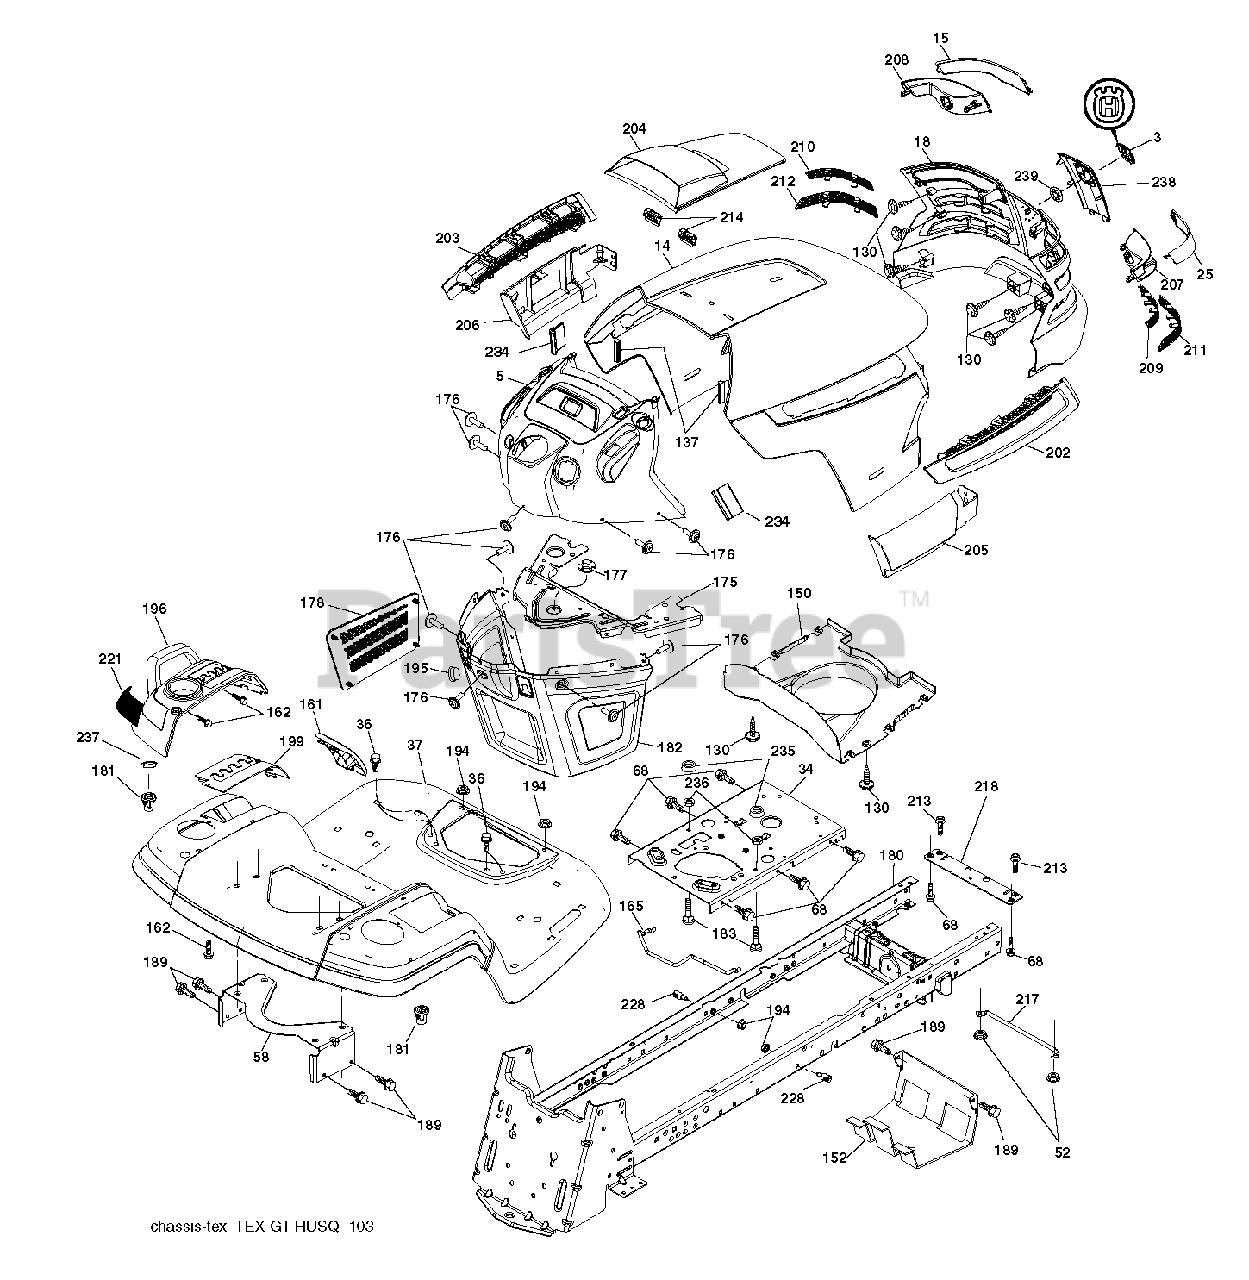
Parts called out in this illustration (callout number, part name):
3	LOGO.HUSQ.GT.LT.CROWN.H
14	HOOD
15	LENS.LH.TEX.GT.HUSQ.CL
18	GRILL.ASM.HUSQ.TG/CRD.W/TRIM
25	LENS.RH.TEX.GT.HUSQ.CL
34	PLATE.ENGINE.WELDED.CHASSIS
36	SCREW 5/16"
37	FENDER.PNT.TX.GT.CH/FW/DL.HUSQ
52	LOCKNUT
58	BRKT.SUPPORT.FNDR/TANK
68	SCREW LT
130	SCREW.#10 X 0.750.BOS
137	BUMPER DASH
150	AIR.DUCT.TEXGT.HUSQ.SV
152	SHIELD.BROWNING.W/TEX
161	CONSOLE.FUEL.WINDOW.HU
162	SCREW.HI-LO.CONSOLE
165	SUPPORT.TANK.REAR.W/TEX
175	PLATE.CROSSMEMBER.HUSQ
176	SCREW.#10-24X5/8.RN.QU
177	BUSHING, STEERING
178	CARGO.ASM.NET.TXGT.W/C
180	CHASSIS.WLDMT.TX.GT.05
181	BUSHING.MNT.FEND.CRGO.
182	DASH.LOWER.COMMON.12V.
183	BOLT.5/16-18X1-1/4 FULL.THREAD
189	SCREW
194	NUT LOCK HEX FLANGE 5/16-18
195	PLUG.HOLE.DASH.LOWER.12V.BLK
196	SUBASM.CONSOLE.HUSQ.GT.DECKLFT
199	PLATE.DECK.LIFT.HUSQVARNA.GT
202	VENT.SIDE.HOOD.RH.HUSQ
203	VENT,SIDE.HOOD.LH.HUSQ
204	HOOD VENT
205	HOOD SIDE SKIRT RH
206	SKIRT.HOOD.SIDE.HUSQ.L
207	BEZEL.RH.TEX.GT.HUSQ
208	BEZEL.LH.TEX.GT.HUSQ
209	INSERT.HEX.GRILL.HUSQ.GREY
210	INSERT.HEX.GRILL.HUSQ.
211	INSERT.HEX.GRILL.HUSQ.
212	INSERT.HEX.GRILL.HUSQ.
213	BOLT
214	CLIP.RETAINER.TINNER.
217	ROD.PIVOT.HOOD
218	X-PIECE.HOOD.STOP.NON/
221	REFLECTOR.LH.TEX GT HU
228	STUD.FASTNER.W/ANTI-ROTATE
234	BUMPER.HOOD.TEX.HUSQVARNA
235	SPACER FENDER
236	NUT.CENTERLOCK.5/16-
237	PLUG.MOUNT.CARGO.BLK
238	TRIM.HUSQ.TG/CRD.SERVICE
239	NUT PUSH M
